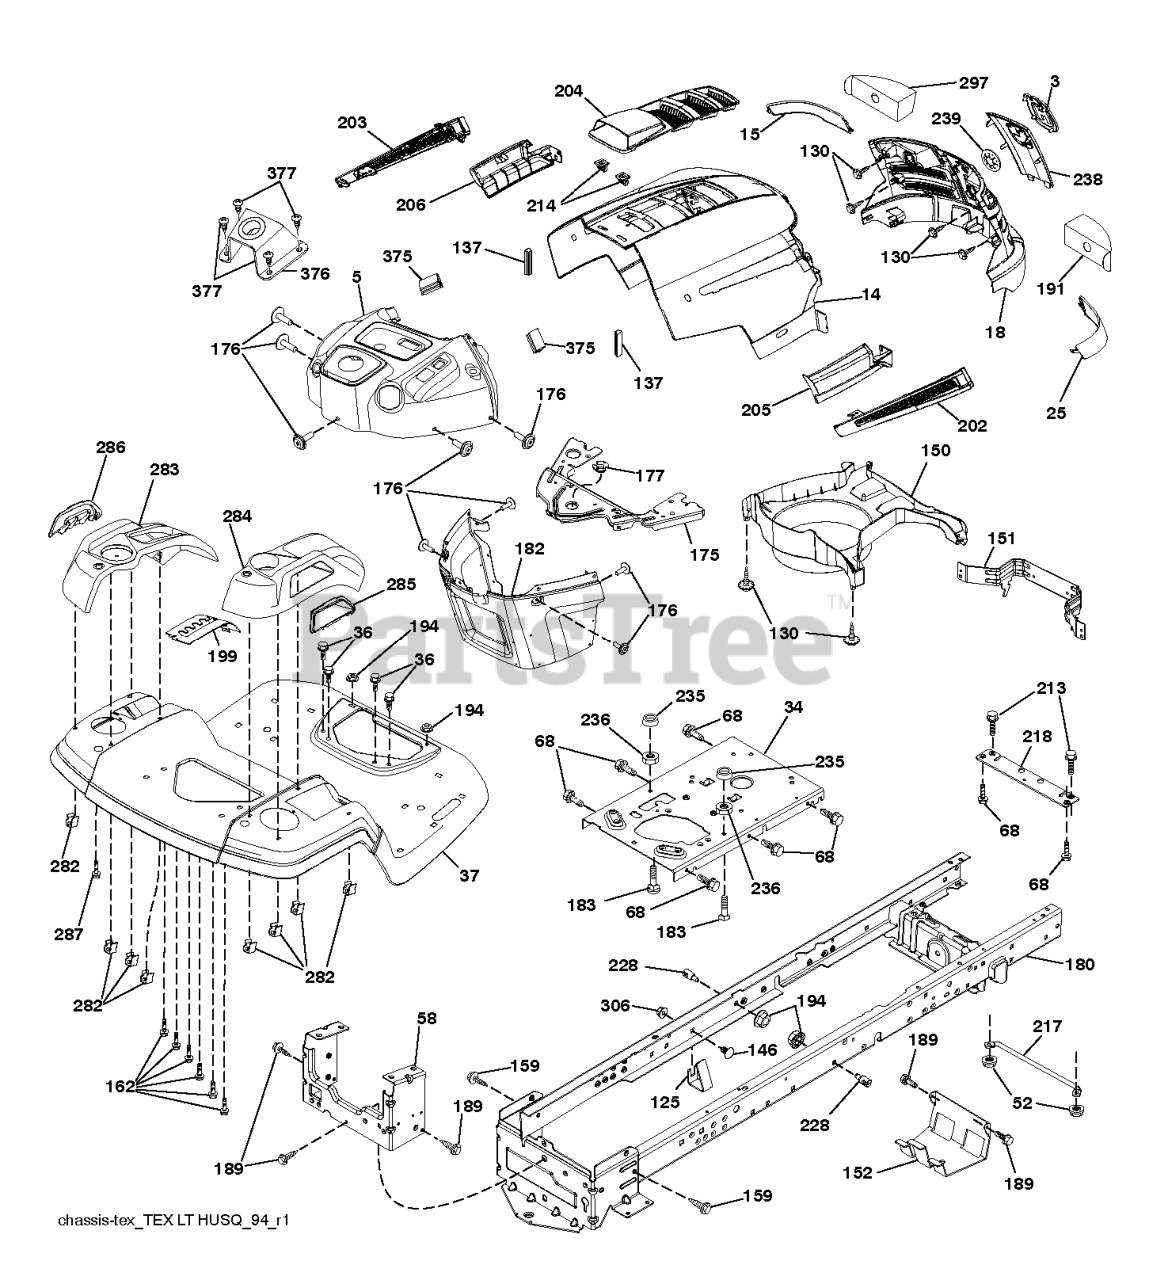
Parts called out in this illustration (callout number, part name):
1	RP DRIVE SHAFT TUBE
1	TUBE
2	SPACER SLEEVE
4	MOVEMENT LIMITER
5	%BAND
6	SPACER SLEEVE
7	GUIDE
8	DRIVE SHAFT
8	SHAFT
9	WARNING DECAL
